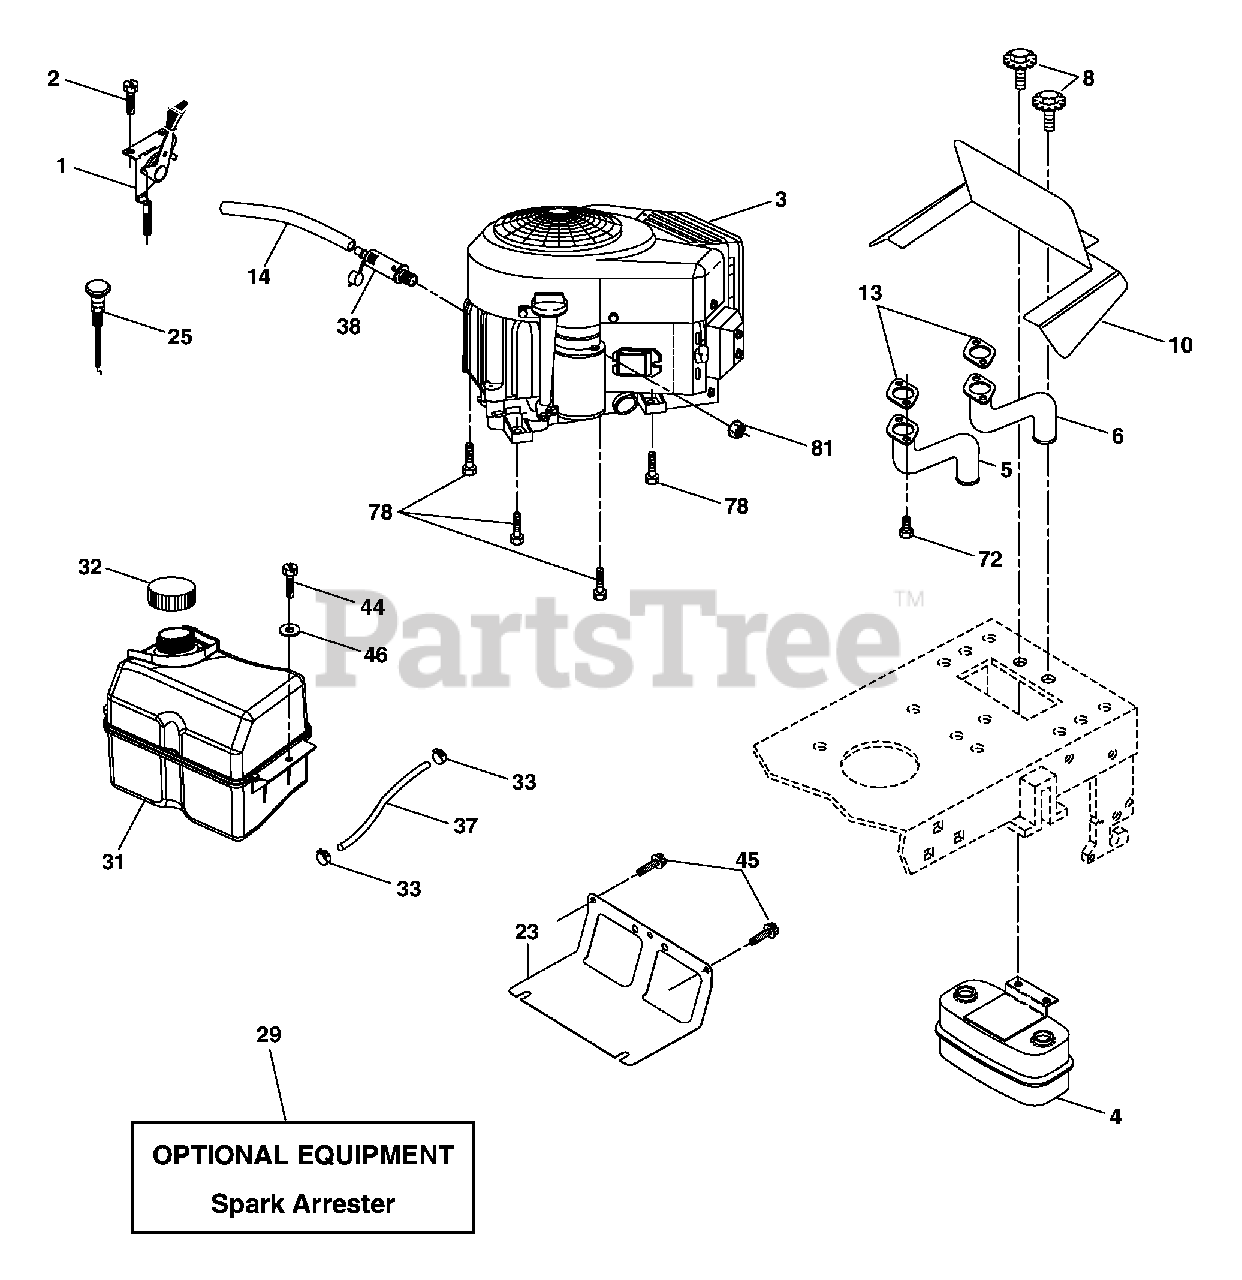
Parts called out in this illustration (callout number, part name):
1	Control, Throttle
2	Screw Hex Thd Cut 1/4-20 x 1/2
4	Muffler
5	Exhaust Tube LH
6	Exhaust Tube RH
8	Bolt 5/16-18 UNC x 3/4
10	Shield Browning
13	Muffler Gasket
14	Tube Oil Drain
23	Shield, Browning/Debris Guard
29	Arrester, Spark
31	Tank, Fuel
32	Cap, Fuel
33	Clamp, Hose Blk
37	Line, Fuel
38	Plug Drain Oil Easy
44	Screw Hex Wsh Thdrol 1/4-20 x 3/4
45	Screw Hex Wsh Thdrol 3/8-16 x 3/4
46	Washer 9/32 x 7/8 x 16 Ga.
72	Screw Hex 5/16-18 x 1
78	Screw 3/8-16 x 1-1/2
81	Nut Keps Hex 1/4-20 unc
